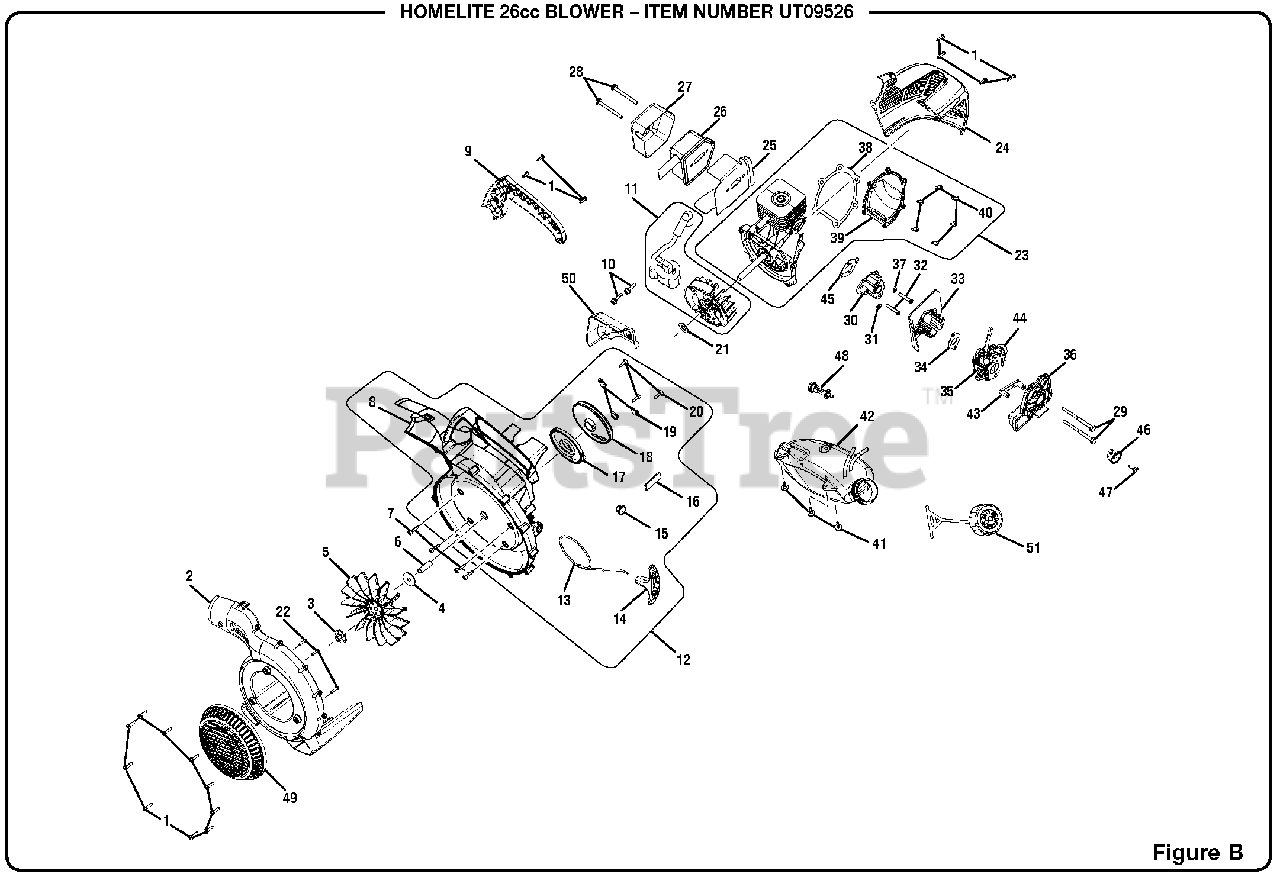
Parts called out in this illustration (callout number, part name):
1	Screw (M4 x 18 mm, T20 Torx Hd.)
2	Outer Volute w/Label
3	Blower Fan Nut
7	Screw (M4 x 17 mm,T20 Torx Hd. T.F.)
8	Inner Volute w/Eyelet and Label
9	Handle Cover
10	Screw (M4 x 19 mm, T20 Torx Pan Hd. T.F.)
11	Ignition Module and Flywheel Kit
12	Lower Housing w/Starter and Label Assembly
13	Starter Rope (42 in.)
14	Starter Grip
17	Spring & Container
18	Starter Pulley
19	Pulley Retainer
20	Screw (M4 x 14 mm, T20 Torx Hd. T.F.)
22	Screws (10-14 x 3/4 in., T25 Torx Pan Hd. T.F.)
23	Short Block Assembly
24	Engine Cover w/Label
25	Muffler Gasket
26	Muffler Assembly
27	Muffler Heat Shield
28	Screw (10-24 x 2-1/8 in.)
29	Screw (M5 x 48 mm)
32	Screw (M5 x 25 mm, T20 Torx Hd.)
34	Heat Dam Gasket
35	Carburetor
36	Air Box Base
38	Crankcase Cover Gasket
39	Crankcase Cover
40	Screw (M4 x 12 mm, T20 Torx Hd.)
41	Screw (M4 x 14 mm, T25 Torx Truss Hd.)
42	Fuel Tank Assembly (Inc. Fuel Lines)
43	Choke Lever
44	Primer Bulb
45	Intake Gasket
46	Choke Plate
47	Screw (M4 x 12 mm, T20 Torx Pan Hd.)
48	Fuel Filter
49	Blower Door
50	Baffle Plate
51	Fuel Cap Assembly (Inc. Tether)
